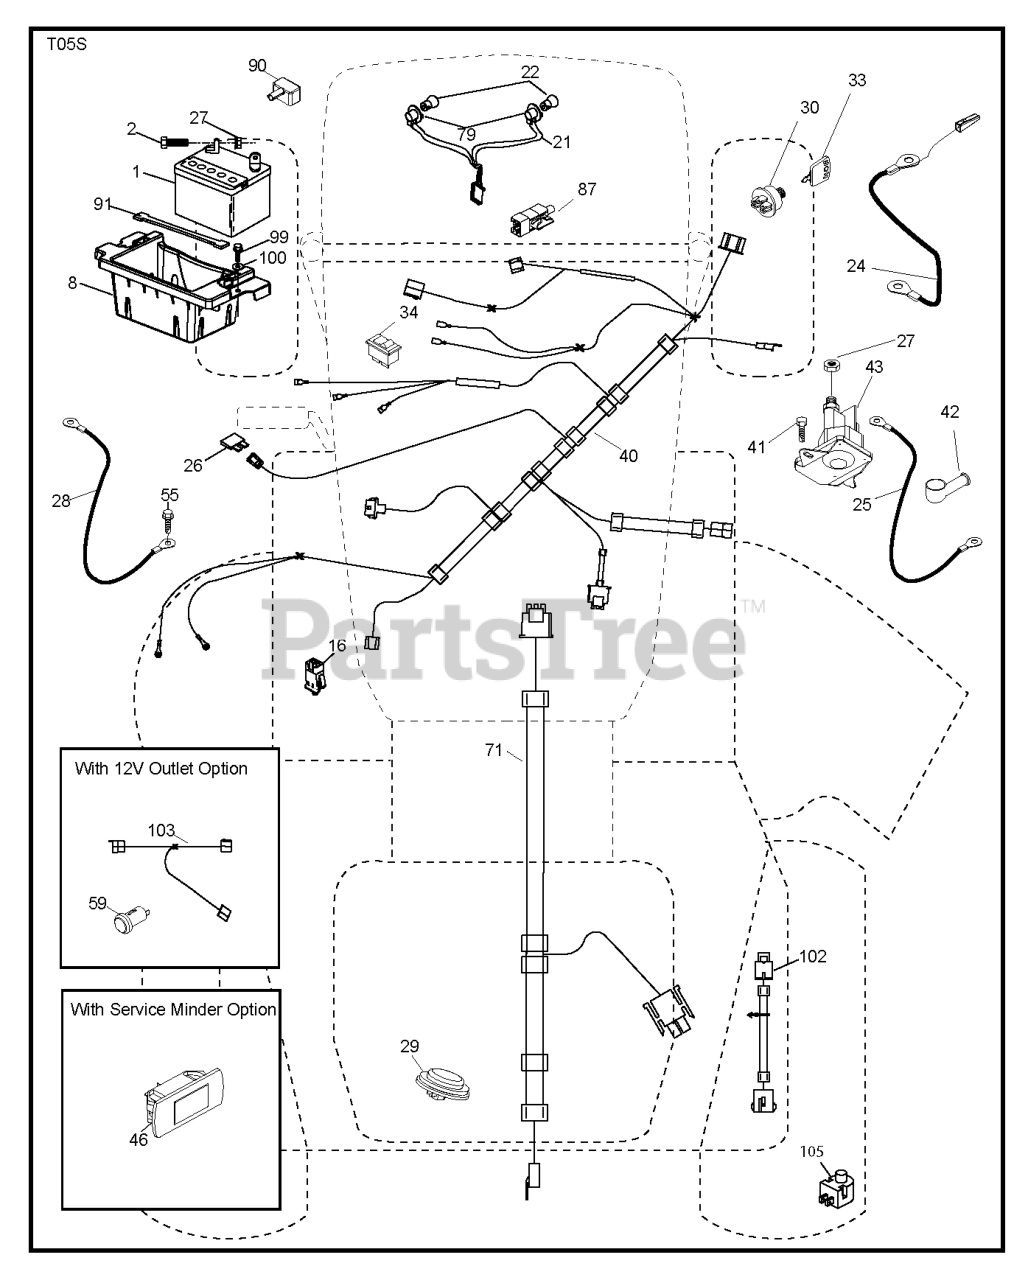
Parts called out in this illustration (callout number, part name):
1	Battery, Dry 30 Amp
2	BOLT.HEX.1/4.X.3/4.DICHROMATE
8	TRAY.ASM.BATTERY.FRT.TEX.CARB
16	SWITCH INTERLOOK PUSH-IN
21	HARNESS.LIGHT W/4152J BULBS
24	CABLE.BATT.POS.WIRE.TG.DA SOL
25	CABLE.STARTER.6G.BL/RED.17.5
26	FUSE 20AMP
27	NUT
28	CABLE GROUND 6 GA 21" 90T BLK
29	SWITCH.SEAT.DELTA.OPC.
30	SWITCH.IGN.DELTA.W.LGH.ROS
33	KEY.CHAIN.BLISTER.PACK.GEN.USA
40	HARNESS IGN. DASH
41	SCREW
42	TERMINAL COVER
43	SOLENOID.W/BRASS.PLUNGER
46	RP.GUAGE.SRVCMNDR.HRMTR.
55	SCREW 5/16"
71	HARNESS-CHASSIS SUB
79	BULB HOLDER ASM.
87	SWITCH.INTRLCK.CLUTCH.
90	COVER.TERMINAL.BATTERY
91	STRAP.BATTERY.MOUNT.FRONT(2 2)
99	SCREW HEXWSHR 1/4-20X3/4
100	WASHER
102	HARNESS PIGTAIL PCH TEX ROS
105	REVERSE SWITCH
